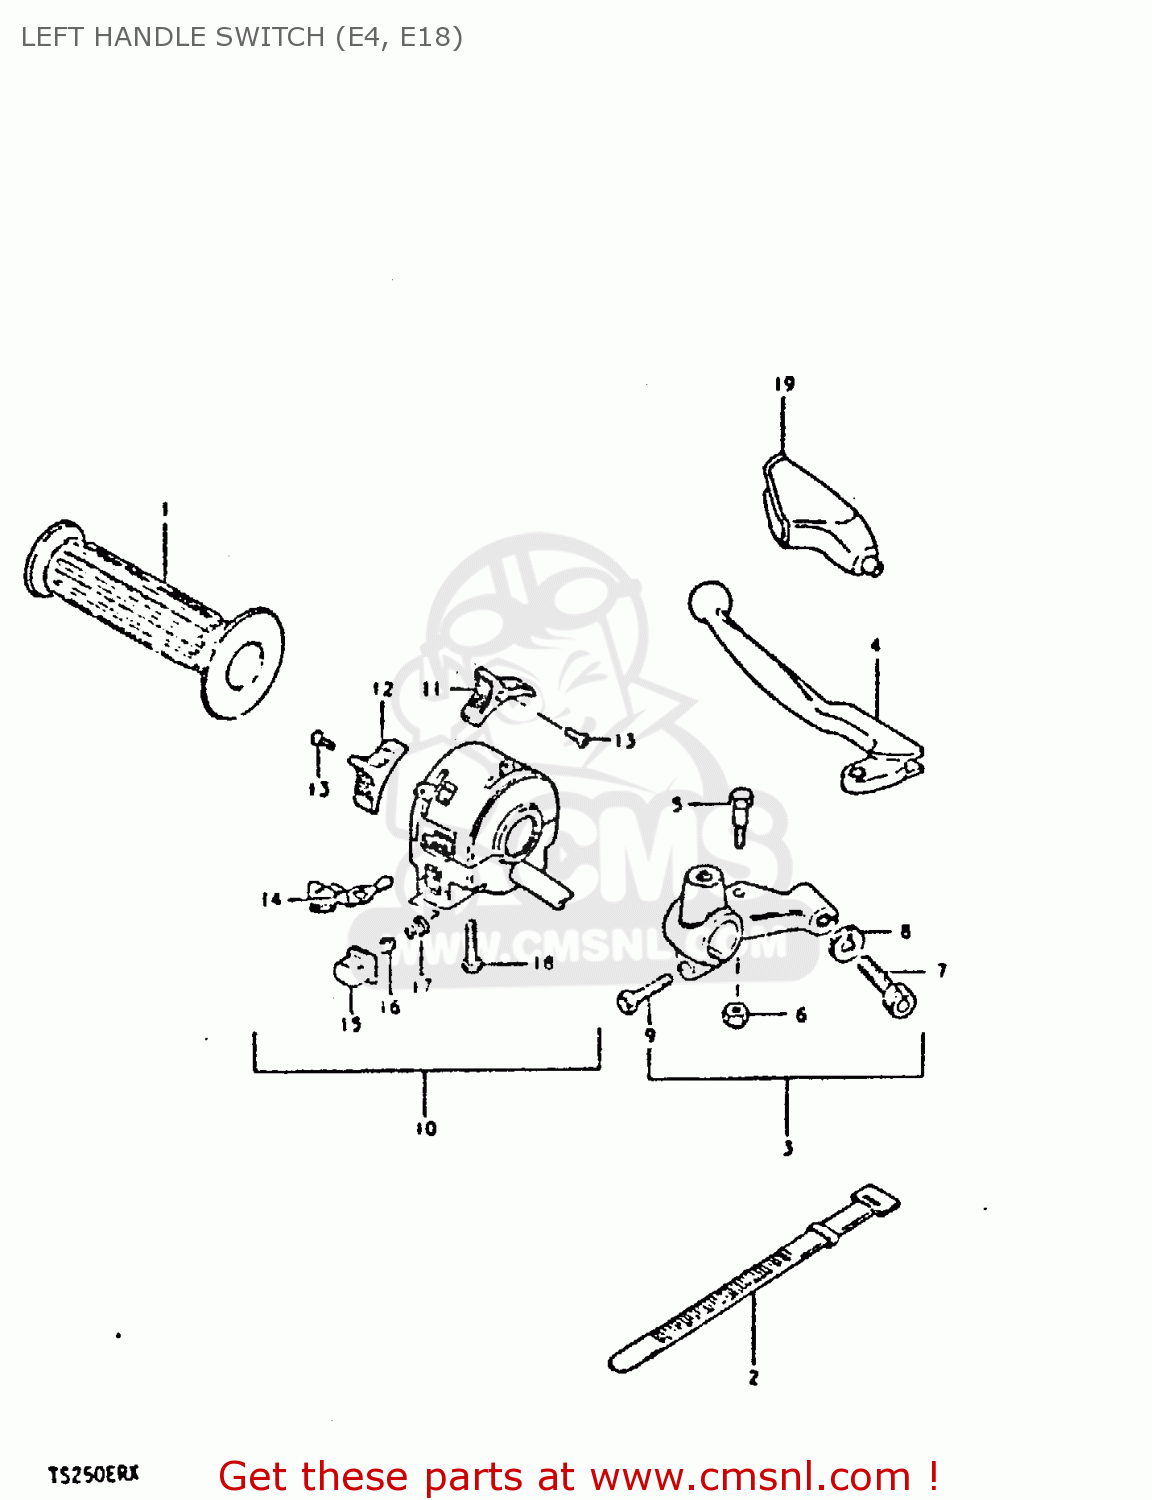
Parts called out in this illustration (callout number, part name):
1	GRIP,L
2	CLAMP(L:120)
3	LEVER ASSY,CLUTCH
4	LEVER,CLUTCH
5	BOLT,LEVER
6	NUT 6MM
7	ADJUSTER,CABLE
8	NUT,CABLE ADJUSTER
9	BOLT
10	SWITCH ASSY,HANDLE,L
11	KNOB,LIGHTING SWITCH
12	KNOB,DIMMER SWITCH
13	SCREW
14	KNOB,TURNSIGNAL
15	BUTTON,HORN
16	CONTACT
17	SPRING
18	SCREW
19	COVER,CLUTCH LEVER
